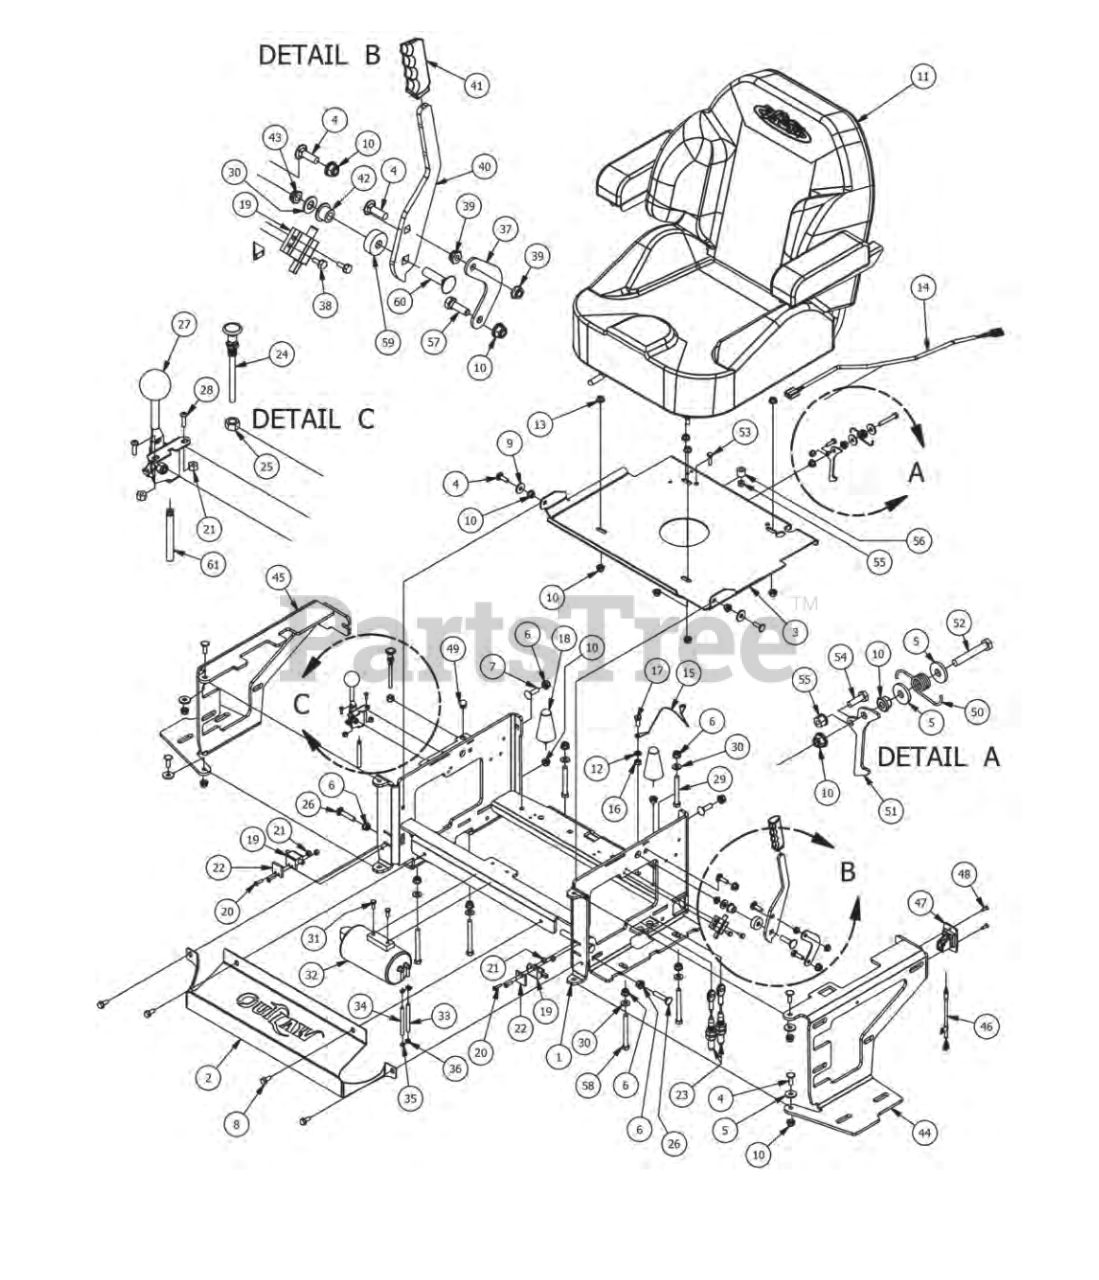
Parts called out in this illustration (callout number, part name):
1	2015 Outlaw Seat Bracket
2	Outlaw Cooler Cover
3	Seat Plate
4	5/16-18 x 1 Carriage Bolts Zinc
5	360 ID Plastic Washer
6	3/8" Nylock Flange Nut
7	3/8" x 1 1/4" Carriage Bolt
8	5/16 x 3/4 washer head type F screw
9	360 ID Plastic Washer-Black
10	5/16" Flange Nut Zinc W/Serrations
11	2015 Outlaw Seat
12	5/16" Lock Washer
13	5/16" Flange Nut
14	Seat Switch Adapter
15	Seat Cable
17	5/16" x 3/4" Hex Bolt
18	Rubber Cone-1621-153
19	Safety Switch
20	10-24 x 1 BS C/S 18-8 SS
21	10-24 Nylon Insert Locknut
22	Switch Block Plastic
23	Long Brake Cable
25	3/8" Fine Threaded Jam Nut
26	3/8 x 1 3/4 Carriage Bolt
27	Universal Throttle Head - 2012
28	10-24 X 5/8 BS C/5 18-8 SS
29	3/8-16x3 grade 5 hex bolt
30	3/8" Flat Washer
31	M6-1.0 X 16MM Hex Bolt
32	Carbon Canister ZT,CZT,Outlaw
33	1/4" vinyl tubing
34	3/16 vinyl tubing
35	3/16" Vinyl Hose Clamp
36	3/16 vinyl clamp
37	Brake Cable Adapter Bracket
38	12-24x 1/2 HWH Bolt
39	5/16-18 Nylock Jam Nut 1/2 Nut
40	Brake Handle Cam Over
41	Rubber Brake Grip-cZT/ZT 2013
42	Bronze Bushing SF-1220-8
43	3/8-16 Hex Flange Top L/N
44	Outlaw 2015 Tank Support (Left)
45	Outlaw 2015 Tank Support (Right)
46	2015 Seat Latch Cable
47	2015 Seat Latch Toggle
48	3/16 Rivet
49	Black Plug-5/8" Head (EFI Engins Only)
50	Torsion Spring for Seat latch
51	Seat Latch Lever
52	5/16-18 X 2 Hex C/S (GR.5) ZC
53	1/4-20 x 1 GR 5 hex bolt zinc
54	1/4-20 x 1-1/4 GR 5 Hex Bolt
55	1/4-20 Nylon Insert flange Nut
56	380x.735x.470 Nylon Spacer
57	5/16" x 1" Bolt
58	3/8-16x3-1/2 grade 5 hex bolt
59	2015 Brake Lever Spacer
60	3/8 x 1 1/2 Carriage Bolt
61	Outlaw Throttle Cable (Cable Only)
